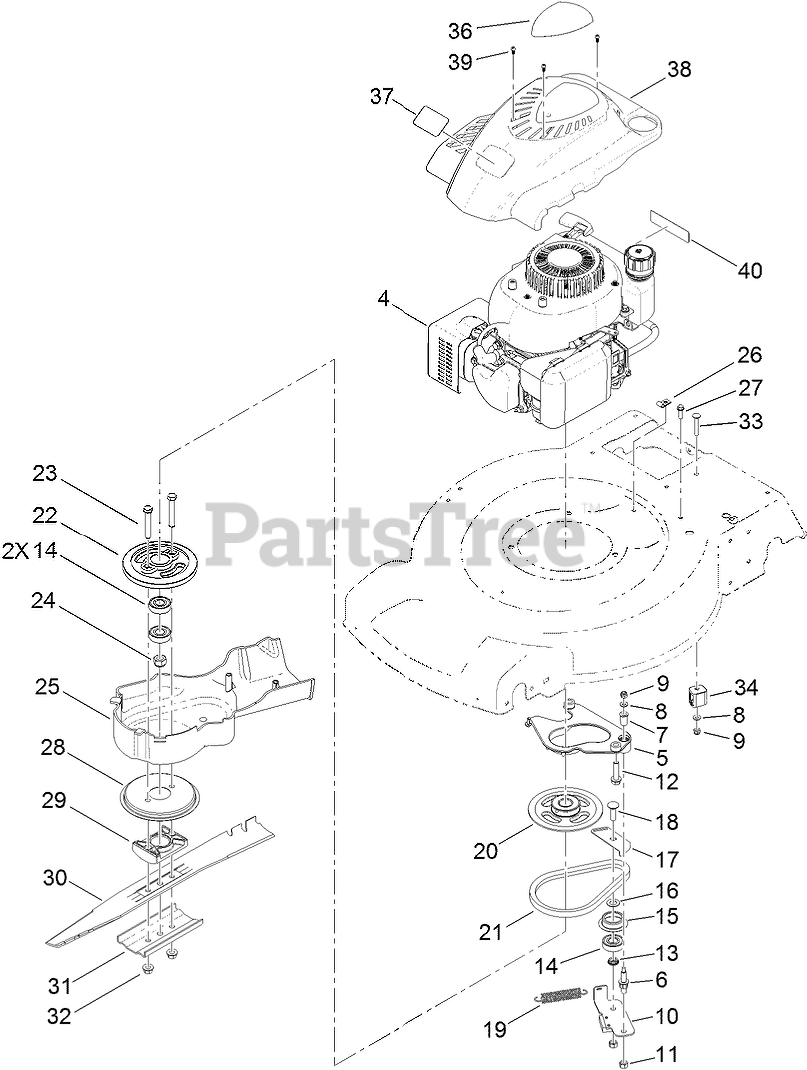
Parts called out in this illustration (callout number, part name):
4	ENGINE-1P65FC
5	PLATE-ANCHOR
6	BOLT-SHOULDER
7	BUSHING
8	WASHER-FLAT
9	NUT-LOCK, NI
10	BRAKE ARM ASM
12	SCREW-HWH
13	SPACER-BEARING
14	BEARING-BALL
15	RETAINER-BELT
16	WASHER-PLAIN
17	PLATE-GUIDE
18	BOLT-CARR
19	SPRING-TENSION, BRAKE
20	PULLEY
21	BELT
22	DRUM
23	SCREW-HH
24	NUT-HEX
26	CLIP-CLOSED, INSULATED
27	SCREW-HWH
28	DISC
29	SUPPORT-BLADE
30	BLADE-22 INCH
31	SUPPORT-BLADE
32	NUT-LOCK
33	SCREW-CARR
34	ANCHOR-CABLE
36	DECAL-SHROUD
38	SHROUD
39	SCREW-PPH
40	DECAL-ARRESTER, SPARK
